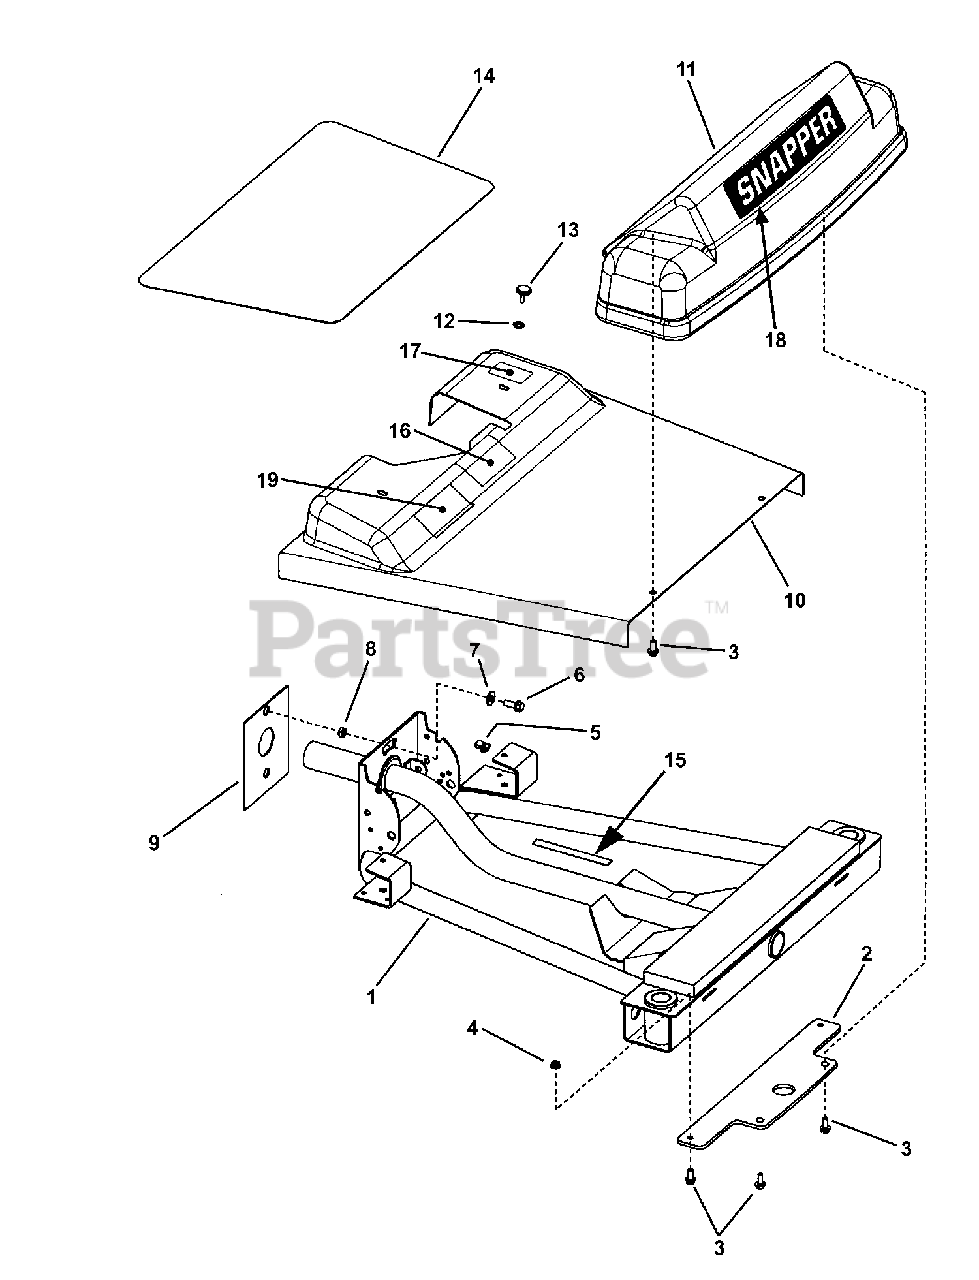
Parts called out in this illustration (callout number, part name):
1	WELDMENT, Front Frame Series #3
2	PLATE, Footrest Support
3	BOLT, 5/16-18 x 3/4" Hex Flange Lock
4	NUT, 5/16-18 Hex Flange Lock, GR 5
5	FASTENER, "U" Type
6	SCREW, 3/8-16 x 1" Hex Washer Self-tap
7	WASHER, 3/8" FLAT (wide)
8	SPACER, Front Frame Pivot
9	PLATE, Front Frame Slip
10	FLOOR PAN, HOZ
11	FOOTREST, HOZ
12	WASHER, 1/4" Internal/External Lock
13	KNOB (1/4-20 thread)
14	MAT, Floor
15	PAD, Floor Board Support
16	DECAL, Warning, Read Manuals & Instructions
17	DECAL, Deck Height
18	DECAL, SNAPPER (14.56" long)
19	DECAL, Chute/Read Manual
